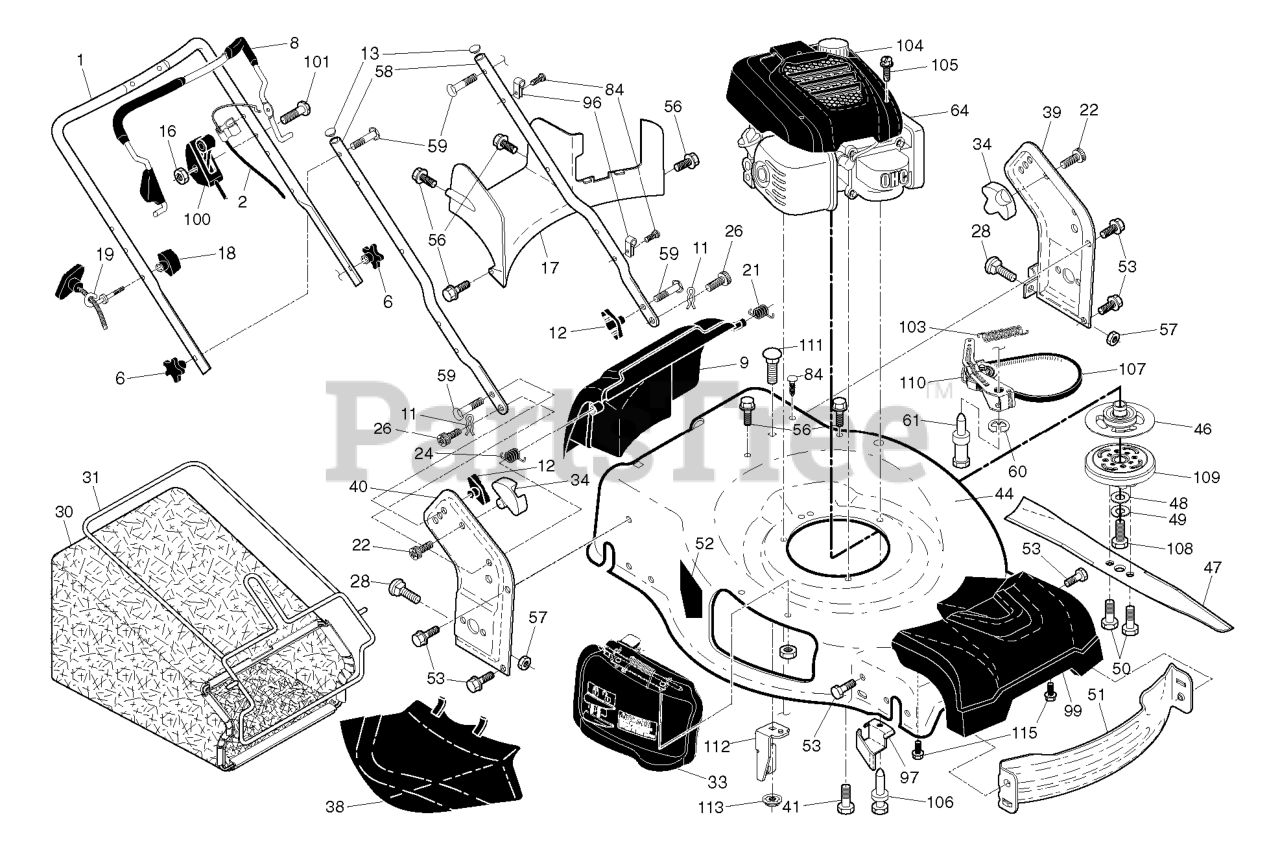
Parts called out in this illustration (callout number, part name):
1	HANDLE.UP.3POS.BS.AW2.GREY
2	CABLE.BBC.22+.AW2.BS.ERGO.WALK
6	KNOB.HANDLE.PLASTIC.STAR.BLACK
8	BAIL.ASM.BBC.EN.ERGO.OM.OR/BK
9	DOOR.REAR.ASM.22+.HUSQ.F/RG.CE
11	COTTER.HAIRPIN.DOOR/HANDLE.PIV
12	KNOB, DEFLECTOR
13	PLUG.PLASTIC.7/8".14-20.GAUGE
16	NUT
17	BAFFLE.REAR.22+RGD.AWD.PLASTIC
18	T-KNOB.NEW ROPE GUIDE
19	GUIDE.ROPE.BLK.ZINC.CHROM
21	SPRING.LH.BLACK
22	SCREW.PAN.HEAD.#10
24	SPRING.RH.GRAY
26	SCREW,DOOR/HANDLE.PIVOT
28	BOLT.CARRIAGE.LN.5/16-18X.5/8
30	GBAG.BA85028ER.GRY/ORG
31	FRAME.GBAG.22+.BLK
33	DOOR ASSY KIT.MULCH DOOR.CE 22
34	BRACKET.GRASSBAG.ATTACHING.BLK
38	DEFLECTOR.CLIPPING.22.BLACK
39	BRACKET.ASM.HANDLE.LT.22+.GREY
40	BRACKET.ASM.HANDLE.RT.22+.GREY
41	BOLT 3/8-16X1-1/8
44	HOUSING.22+RG.MC.WO.BBC.668.TR
46	PULLEY.BBC.DRIVING
47	RP.BLADE.22.4N1.BBC.RUST PREV
48	WASHER.CRANK.BOLT
49	LOCKWASHER
50	BOLT.BLADE
51	BAFFLE.FRONT.22.PLUS
52	DECAL.INTERNATIONL.CUTFINGER
53	BOLT.5/16HEX.WHS.HD
56	SCREW.HX.13X.750
57	NUT.FLANGE.5/16
58	HANDLE.LOWER.22+.BT.GRAY
59	BOLT, HANDLE 5/16-18X1.75
60	E-RING.12MM.SHAFT
61	BOLT.BBC.TENSION.PIVOT
84	FASTENER.PUSH.O.250X0.783
96	CLIP.CABLE.BLK
97	BRACKET.BELT.GUIDE.22+.BZP
99	COVER.ASM.FRONT.HUSQ.22+RGD
100	CONTROL.THROTTLE.HOND.BBC.58.5
103	SPRING.BRAKE.RESET
104	SHROUD.ASM.HONDA.HUSQVARNA
105	SCREW.SHROUD.HONDA
106	BOLT.BRAKE.RESET.SPRING
107	BELT.COG.BBC
108	SCREW, HEX HD 3/8-24 X 1-3/8
109	HUB.FREE.BBC.ASSEMBLY(2 2MC)
110	ARM.BBC.TNSION.ARM.PULL(2 2MC)
112	BRACKET.CABLE MOUNTING.22+
113	NUT.FLANGE.1-4-20-SERR
115	SCREW.HI-LO. 5/16 X 1.00
